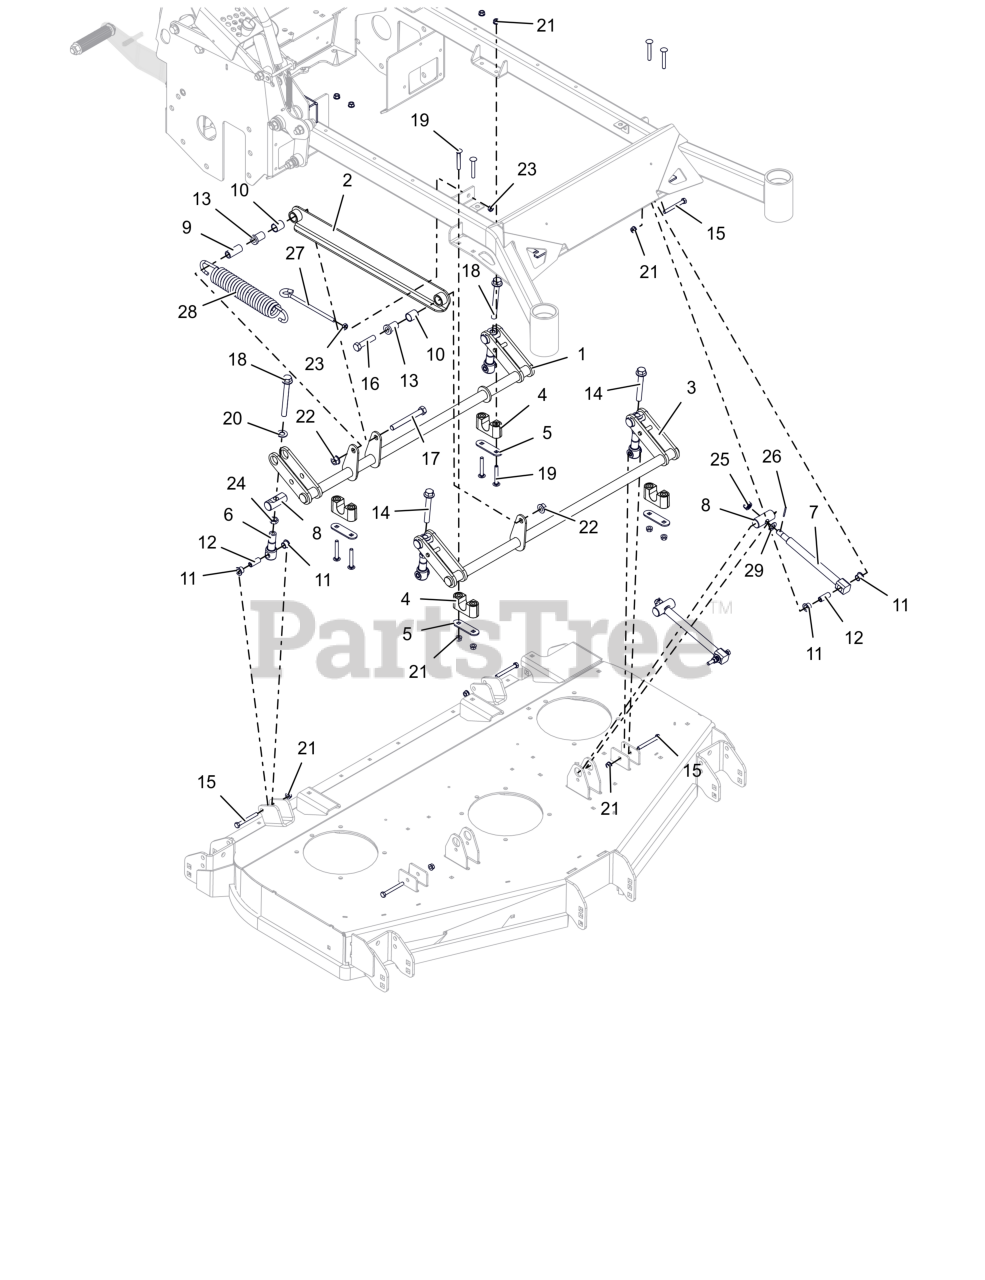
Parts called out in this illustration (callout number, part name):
1	WLDMT- DECK LIFT
2	LINK- DECK LIFT (BLACK)
3	WLDMT- DECK LIFT - FRONT
4	ASM-BUSHING, DECK LIFT
5	PLATE, BEARING SUPPORT
6	LINK, DECK LIFT FORMED
7	DRAG,LINK-HD
8	PIN, DECK LIFT
9	BUSHING- .515 X 1.000 X 3.088
10	BRG- .750 X .875 X 1.000
11	BSHG, FLANGED .50X.625X.50X.062
12	SPCR, .31X.50X1.265
13	BSHG-FLG .515X.746X1.290X1.000
14	BLT, .500-13 X 3.500 GR5 ZC
15	BLT, HEX .31-18X2.75 G5 ZCC
16	BLT, HEX .50-13X2.25 G5 ZCC
17	BLT, HEX .50-13X4.25 G5 ZCC
18	BLT, HEX-FLG .50-13 X 4.5 GR5 ZC
19	BLT, RHSSN.31-18X2.25 G5 ZCC
20	WSHR, FLT .557X1.040X.102 ZCC
21	NUT,LK-CTR-FLG .31-18 GF ZCC
22	NUT-LK-CTR-FLG .500-13 GG ZCC
23	NUT-JAM .375-16 G2 ZCC
24	NUT-JAM .500-13 G2 ZCC
25	NUT-SL .50-13
26	PIN,CTR.12X1.25EXTPRSQCT ZC120
27	BOLT, .38-16X6.00 .62 DIA EYE
28	SPRG-EXTEN - .273X1.853X10.125
29	WSHR, BLVL .531 X 1.000 X .062 MZ
